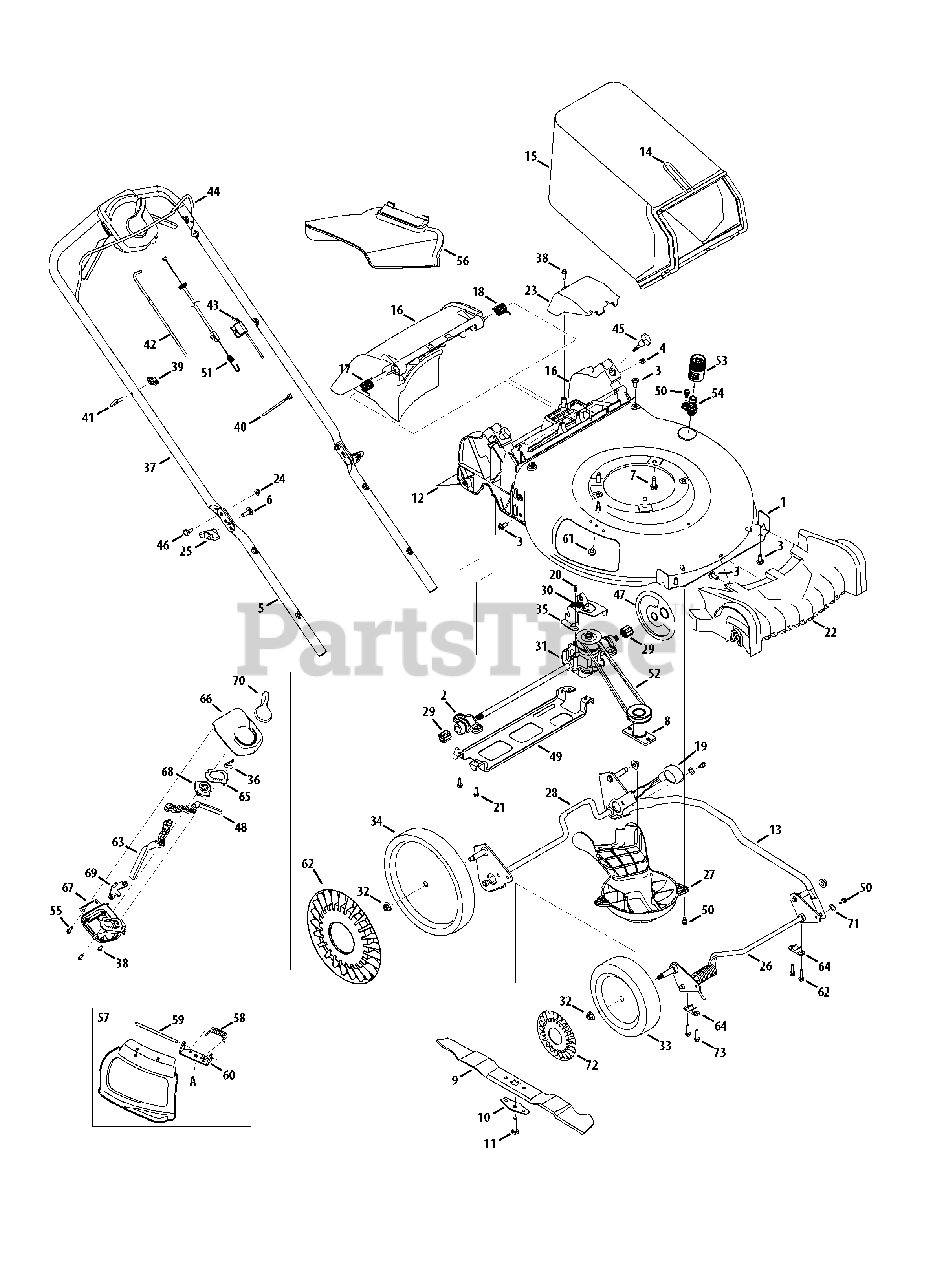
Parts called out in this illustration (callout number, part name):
1	21" Deck Ass’y
2	Bearing Assembly
3	Hex Hd. Cap Scr. 5/16-14 x .75
4	Sq. Nut 1/4-20
5	Lower Handle
6	Carriage Bolt 5/16-18
7	Hex Wash HD Tap Scr 3/8-16 x .88
8	Blade Adapter
9	21" Mulching Blade
10	Blade Bell Support
11	Hex Bolt 3/8-24 x 1.5" Lg. (Gr 8)
12	Trailing Shield 4.54 x 17.37
13	Cross Bracket
14	Catcher Frame
15	Grasscatcher Bag
16	Rear Baffle Ass’y (Incl. door)
17	RH Torsion Spring
18	LH Torsion Spring
19	Knob (Black)
20	Sems TT Scr. 1/4-20 x .50
21	Screw 1/4-15 x 1.25
22	Front Axle Cover
23	Transmission Cover
24	Flanged Lock Nut 1/4-20 Gr. F Nylon
25	Wing Knob-Black
26	Front Axle Ass’y
27	Engine Baffle
28	Rear Axle Ass’y
29	Spur Gear 9T
30	Extension Spring 2.405
31	Transmission Ass’y
32	Flange Locknut 3/8-16 Gr. F Nylon
33	Front Wheel
34	Rear Wheel
35	Transmission Bracket
36	Spring
37	Upper Handle - Black
38	Screw, 1/4-15 x .750
39	Knob 1/4-20
40	Cable Tie
41	Rope Guide Bolt
42	Drive Cable
43	Control Cable (Honda)
44	Blade Control (Black)
45	Knob 1/4-20 x 1.73 Black
46	Shoulder Screw .375 x .126 x 1/4-20
47	Dust Cover
48	Control Lever LH
49	Rear Support Bracket
50	Shoulder Scr. 1/4-20 x .50
51	Speed Adjustment Cable
52	V Belt
53	Water Nozzle Adapter
54	Deck Water Nozzle
55	Shoulder Screw 1/4-15 x .970
56	Chute Deflector
57	Mulching Plug Ass’y (Incl. ref. no. 58-60)
58	Torsion Spring
59	Hinge Pin
60	Chute Deflector Bracket
61	Screw 1/4-20 x .50
62	Hub Cap - 11"
63	Control Lever RH
64	Bushing .505 Dia. x .62
65	Cable Adjust Plate
66	Upper Housing
67	Lower Housing
68	Speed Adjust Actuator
69	Drive Cable Actuator
70	Speed Select Lever
71	Wave Washer
72	Hub Cap 8"
73	Screw
